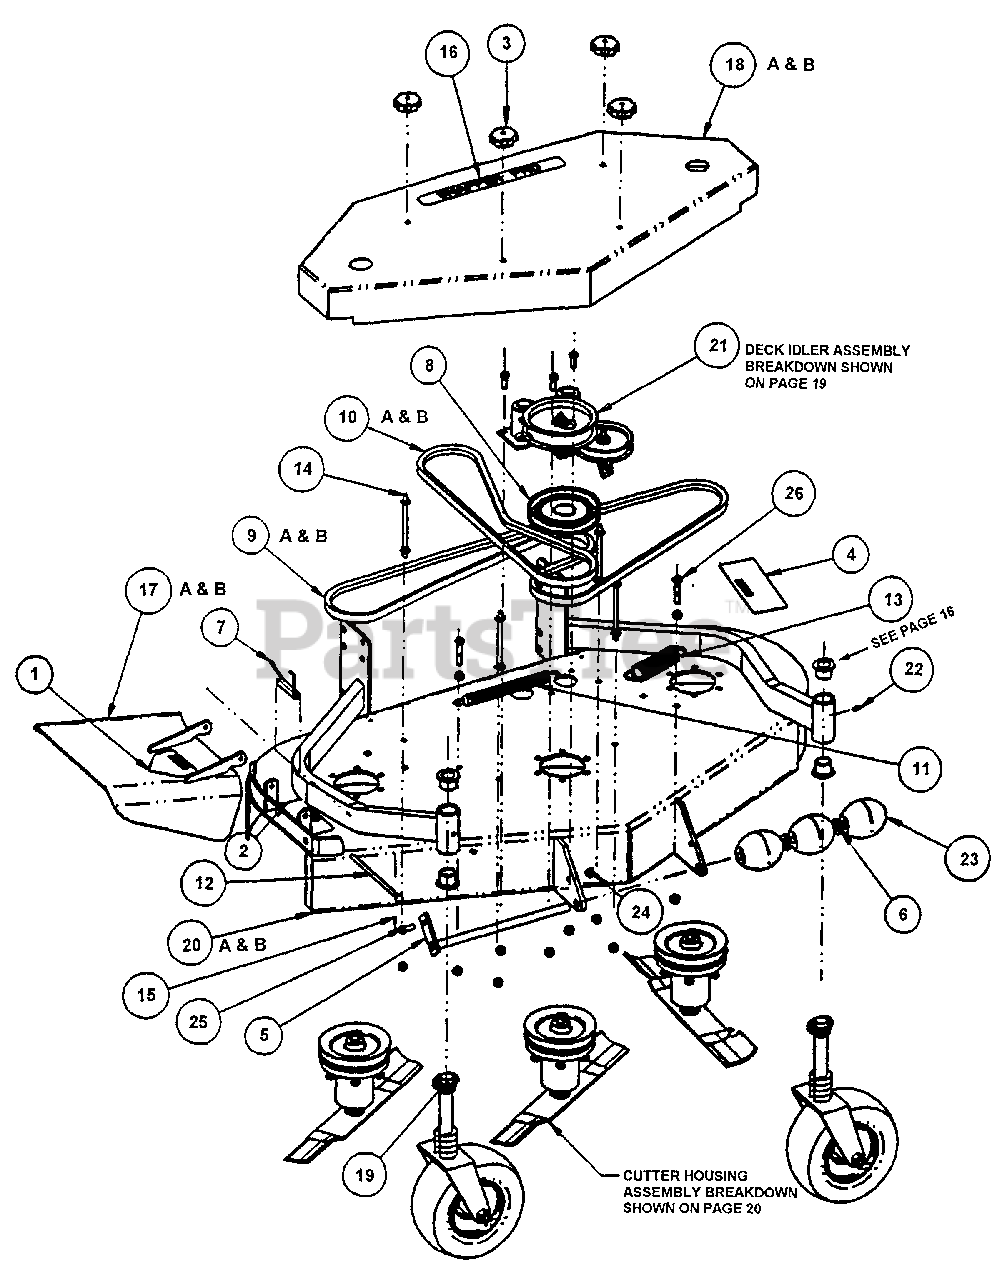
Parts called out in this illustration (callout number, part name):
1	DECAL, Warning (CPSC Cut Finger)
2	DECAL, Warning
3	KNOB, Hood
4	DECAL, Caution- Operator Instruction
5	PIVOT, Roller Pin (Weldment)
6	WASHER, 5/8 Flat
7	SPRING, Chute
8	PULLEY, Driven 5-3/4 O.D
9A	V-BELT, Secondary 48" (113" Long)
9B	V-BELT, Secondary 52" (120" Long)
10A	V-BELT, Primary 48" (66" Long)
10B	V-BELT, Primary 52" (69" Long)
11	SPRING, Extension Primary Idler
12	PIN, Chute Hinge
13	SPRING, Idler
14	STANDOFF, 4-1/2" Long
15	PIN, 3/32 x 1" Cotter
16	DECAL, Snapper Pro
17A	DEFLECTOR, 48" Chute
17B	DEFLECTOR, 52" Chute
18A	ASSEMBLY, Cover 48"
18B	ASSEMBLY, Cover 52"
19	ASSEMBLY, Caster Red (Fixed Decks)
20A	ASSEMBLY, Deck 48" (Fixed Height)
20B	ASSEMBLY, Deck 52" (Fixed Height)
21	ASSEMBLY, Idler - 3 Spindle Deck
22	FITTING, Lube 1/4-28 Straight
23	ROLLER, Low Density Polethylene
24	NUT, 3/8-16 HEX NYLON LOCK
25	BOLT, 3/8-16 X 1" GD5 CZ
26	BOLT, 3/8-16 X 2, GD5, CZ
